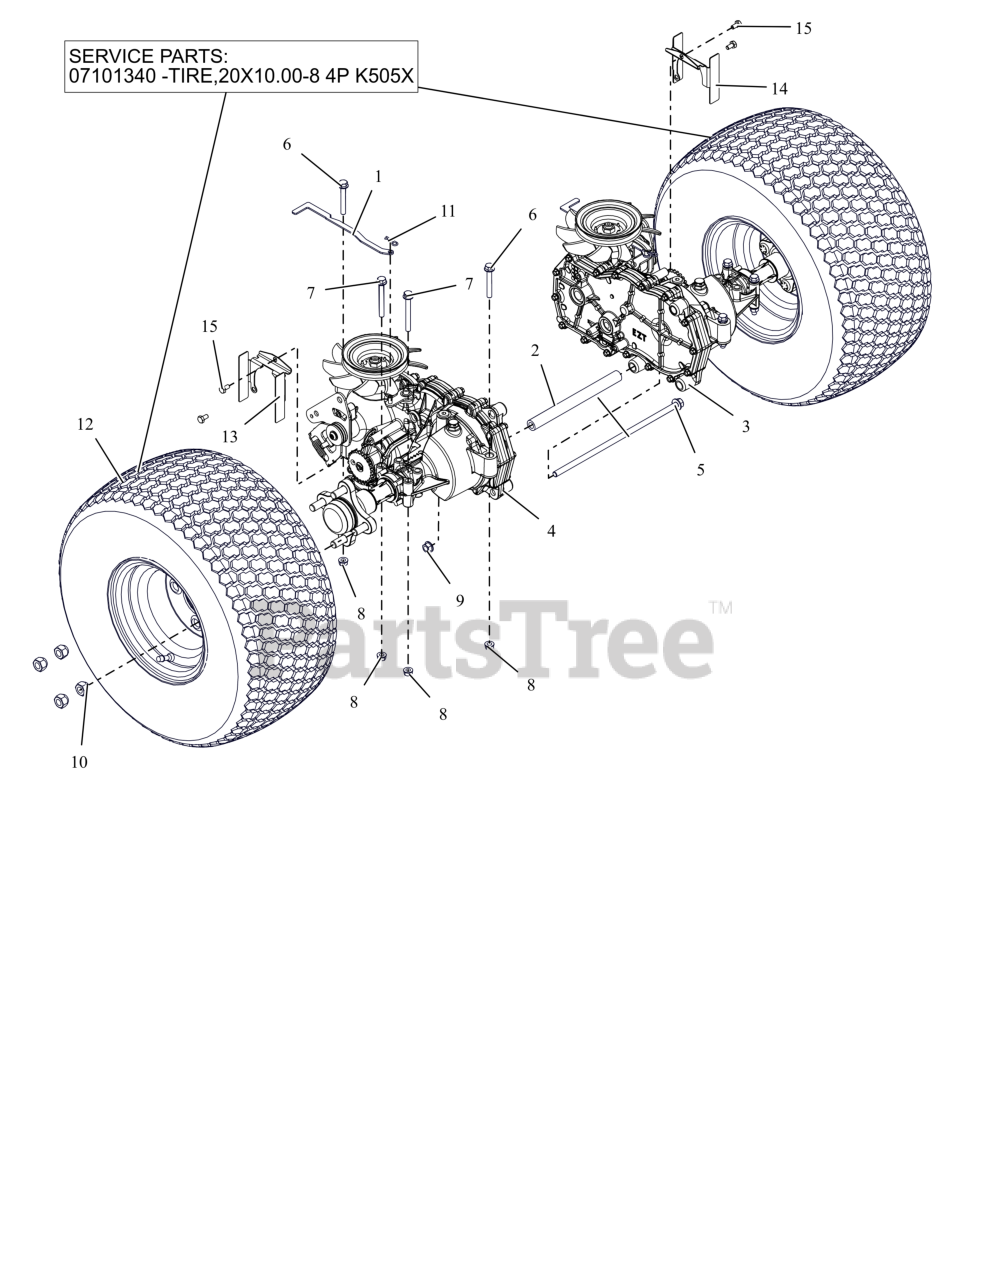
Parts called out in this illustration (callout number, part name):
1	BRKT, DUMP VALVE
2	TUBE, TRANSAXLE BRACE 8.18LG
3	TRANSAXLE
4	TRANSAXLE
5	BLT,HEX-FLG .38-16X11.5 G5 ZCC
6	BLT,HEX-FLG .31-18X2.25 G5 ZCC
7	BLT,HEX-FLG .31-18X2.75 G5 ZCC
8	NUT,LK-CTR-FLG .31-18 GF ZCC
9	NUT-LK-CTR-FLG .375-16 GF ZCC
10	NUT, WHEEL .50-20 ZCC
11	PIN, HAIR #213 .08X1.19 ZCC
12	ASSM TIRE\WHEEL, 20 X 10 -8
12	LAWN TIRE REAR, 4 PLY kK505 20/10.00-8
12	VALVE STEM ASS'Y
12	TIRE TUBE 18/6.50/8.50/9.50-8, 20/8.00/10.00-8 4 PLY TR13 STRAIGHT VALVE
13	GUARD, PARKING BRAKE RH
14	GUARD, PARKING BRAKE LH
15	BLT,HEX .25-20X.50 G5 ZCC
